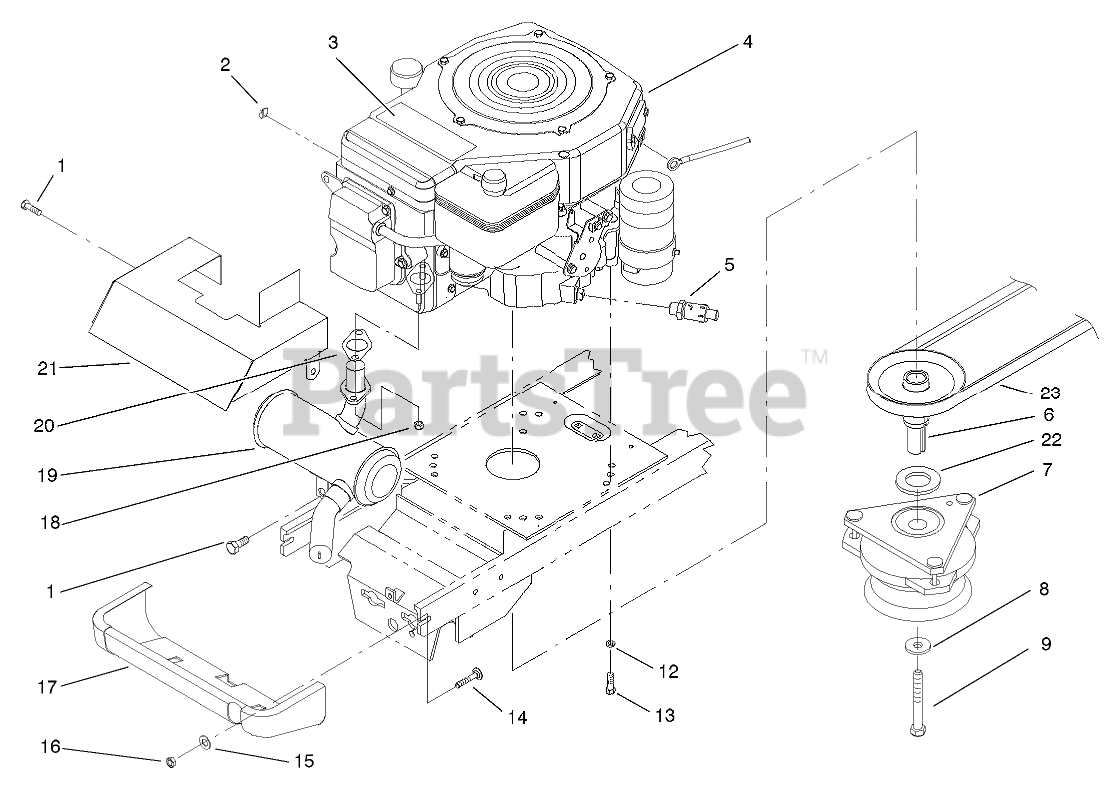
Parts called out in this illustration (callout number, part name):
1	SCREW-HWHTF
2	CLIP-RETAINER, WIRE
3	DECAL - LOGO
4	Engine-Kohler 15
5	VALVE-DRAIN, OIL
6	PULLEY-ENGINE, SLOW
7	CLUTCH-PTO
8	WASHER
9	SCREW-HH
12	WASHER-LOCK
13	SCREW-HH
14	BOLT-CARR
15	WASHER-FLAT
16	NUT-LOCK, NI
17	MUFFLER SHIELD ASM
18	NUT-HF
19	MUFFLER
20	Gasket-Exhaust
21	BAFFLE-MUFFLER SINGLE
22	SPACER-CLUTCH
23	V-BELT
